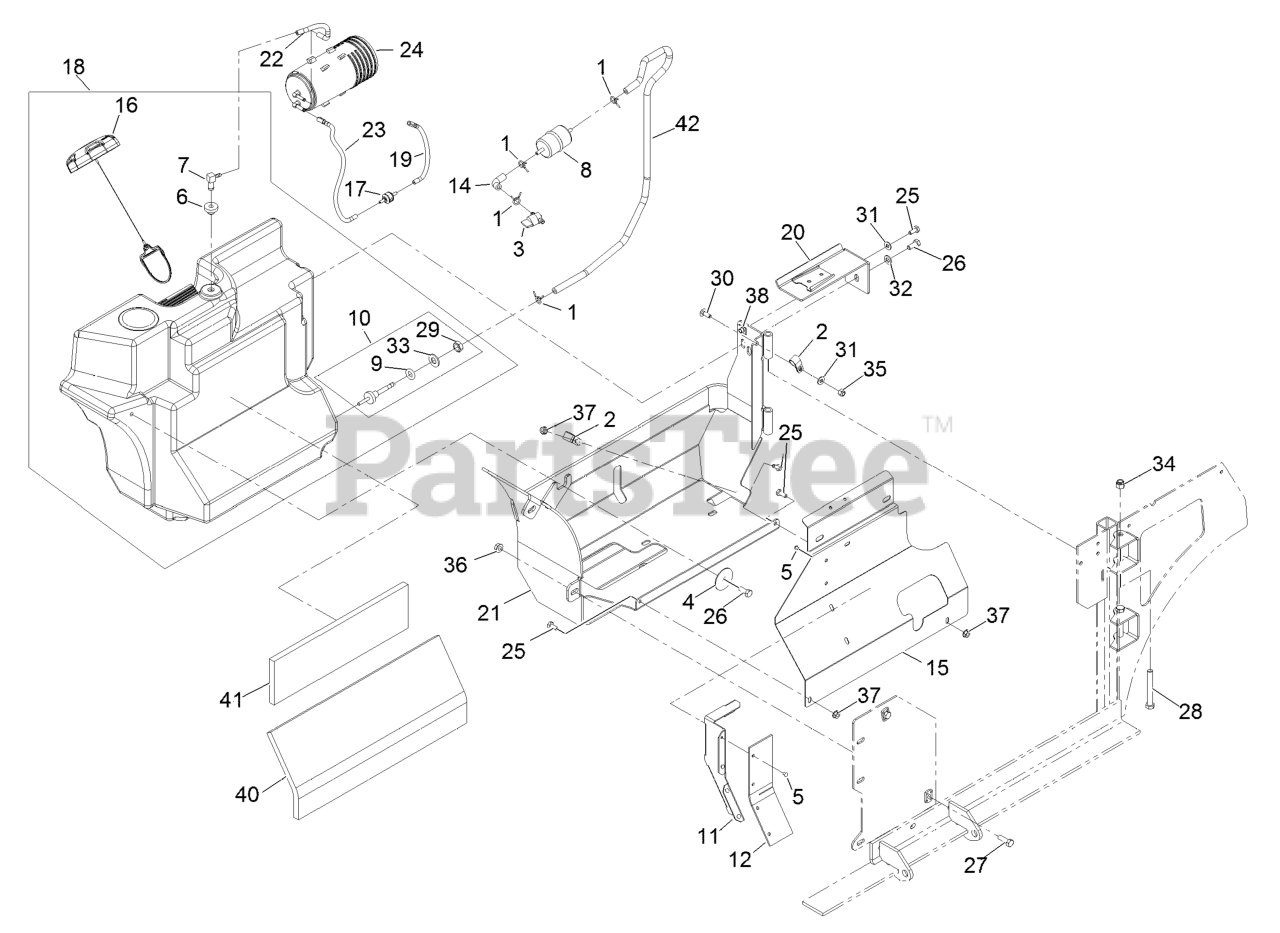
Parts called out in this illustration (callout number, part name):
2	CLIP-LOOM
3	VALVE-FUEL
5	RIVET-POP
6	BUSHING
8	Part No. 2405010 Fuel Filter
9	O-RING,BULKHEAD FITTING
10	FITTING-FUEL, BULKHEAD
11	Deflector, Air
12	FLAP-RUBBER
14	HOSE-FUEL
15	PANEL-TANK SHIELD
18	ASM-FUEL TANK
19	HOSE-VENT, FORMED
20	CANISTER BRACKET ASM
21	TANK FRAME ASM
22	HOSE-VENT, FORMED
23	HOSE-VENT, FORMED
24	CANISTER-CARBON, 800CC
25	SCREW-HH
26	SCREW-HH
27	SCREW-HH
28	SCREW-CARR
29	NUT-JAM
30	BOLT-CARR
31	WASHER-FLAT
32	WASHER-PLAIN
33	WASHER-FLAT
34	NUT-LOCK, NI
35	NUT-LOCK, NI
38	Nut-Retainer-Panel 1/4-20
40	INSULATION-FOAM PAD, REAR
41	INSULATION-FOAM PAD, FRON
42	FUEL LINE ASM
